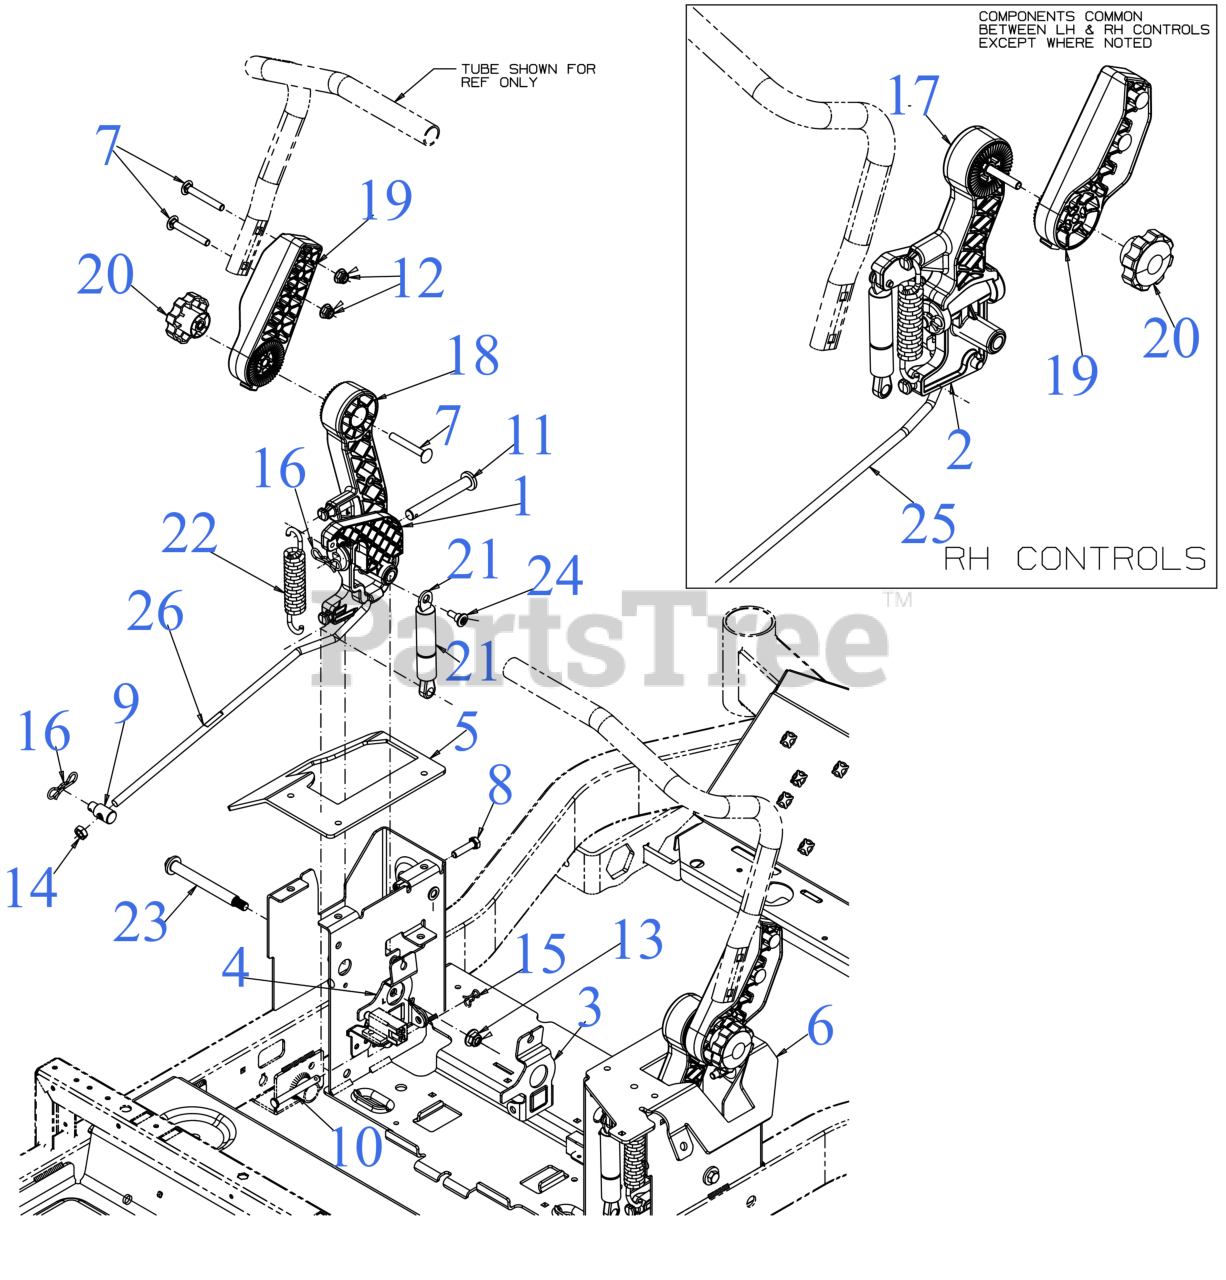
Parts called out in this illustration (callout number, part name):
1	CONTROL ACTUATOR (LH)
2	CONTROL ACTUATOR (RH)
3	BRAKE CABLE LEVER (RH)
4	BRAKE CABLE LEVER (LH)
5	CONTROL TOP BRACKET (LH)
6	CONTROL TOP BRACKET (RH)
7	BOLT 5/16-18 x 2.50 GR1
8	SCREW 5/16-18 x 1.25 GR5
9	CONTROL ROD FERRULE
10	CLEVIS PIN 5/16 DIA
11	CLEVIS PIN
12	FLANGE LOCK NUT 5/16-18
14	HEX JAM NUT 3/8X24
15	BOW TIE COTTER PIN 1/4-5/16
16	BOW TIE COTTER PIN
17	LAPBAR ACTUATOR (RH)
18	LAPBAR ACTUATOR (LH)
19	UPPER ADJUSTMENT HANDLE
20	HAND KNOB 5/16-18
21	DAMPNER CYLINDER
22	EXTENSION SPRING .57 x 5.38
23	SHOULDER SCREW .491x3.937 3/8-16
24	SHOULDER SCREW .394X.280:1/4-14
25	HYDRO CONTROL ROD (RH)
26	HYDRO CONTROL ROD (LH)
